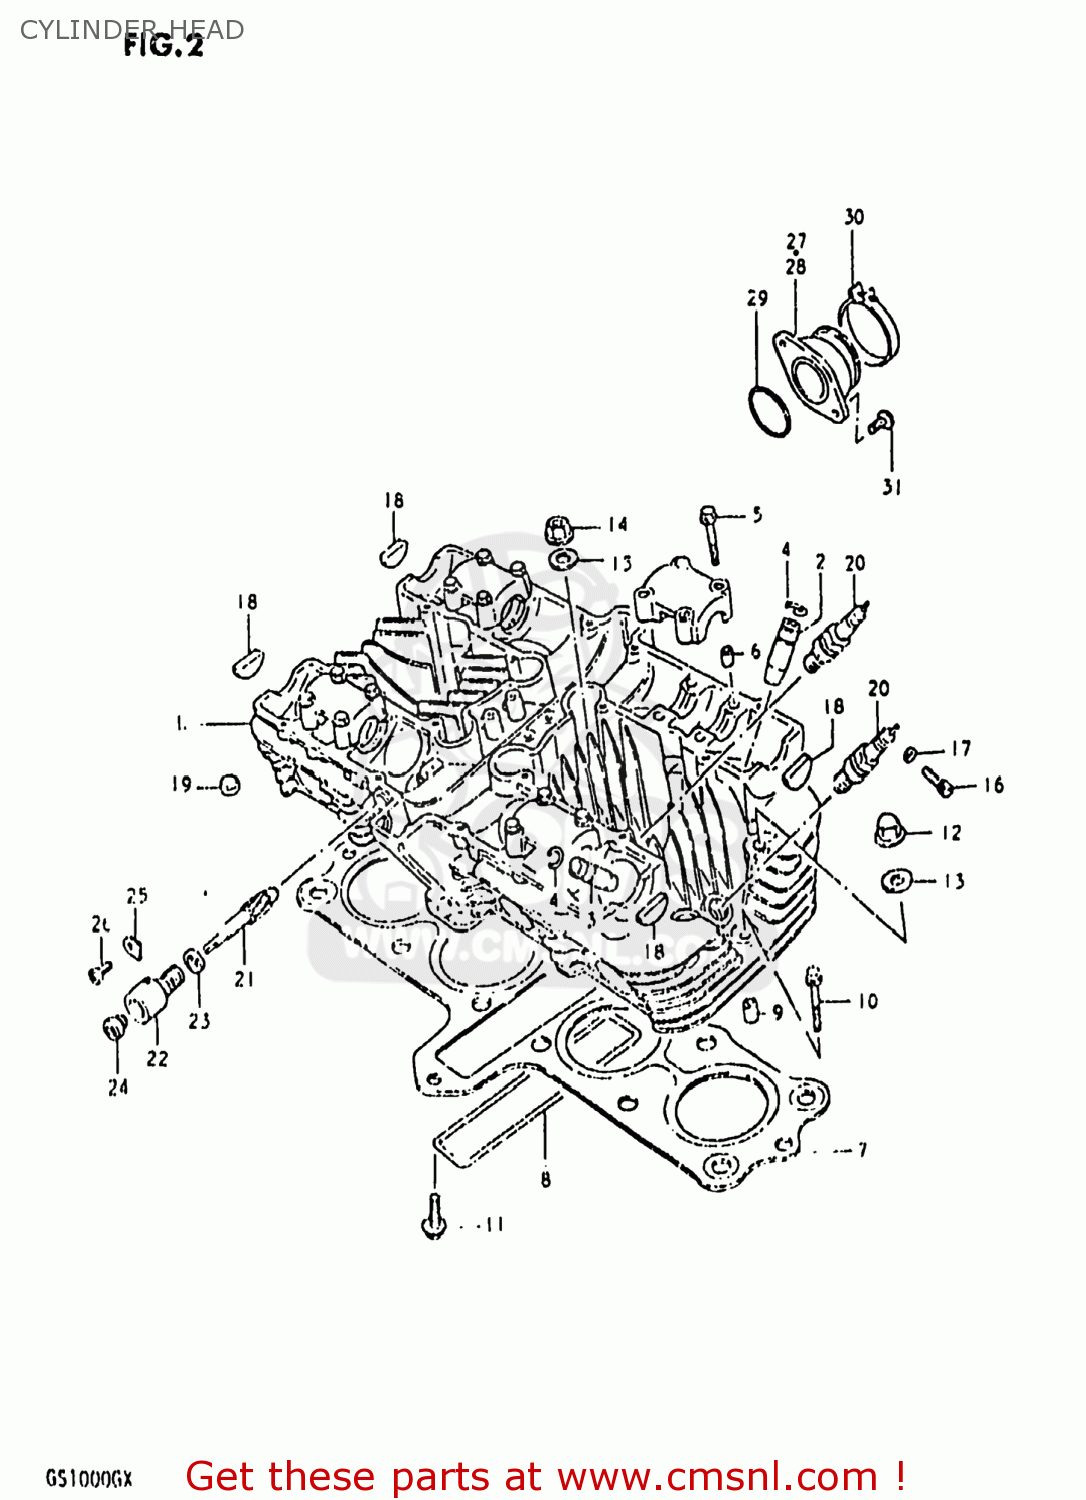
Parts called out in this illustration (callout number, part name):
1	HEAD ASSEMBLY,CYLINDER
2	GUIDE,INTAKE VALVE
3	GUIDE,EXHAUST VALVE
4	RING,SNAP
5	BOLT(6X39)
6	PIN(6.2X8X11)
7	GASKET,CYLINDER HEAD (MCA)
8	O RING(D:3,ID:26X157)
9	PIN
10	BOLT,UNDER
11	BOLT
12	NUT
13	GASKET (NAS)
14	NUT
15	WASHER(10.5X22X2.3)
16	BOLT
17	GASKET(5.3X9.3X1.2) (NAS)
18	PLUG
19	PAD
20	SPARK PLUG
21	GEAR,TACHOMETER DRIVEN
22	SLEEVE,TACHOMETER DRIVE
23	SEAL,TACHOMETER DRIVEN
24	SEAL,OIL(5X12X8)
25	PLATE,TACH DRIVE GEAR SLEEVE
26	SCREW(5X12)
27	PIPE,INTAKE,R
28	PIPE,INTAKE,L
29	O-RING (D:2.4 ID:39.7)
30	CLAMP
31	SCREW
